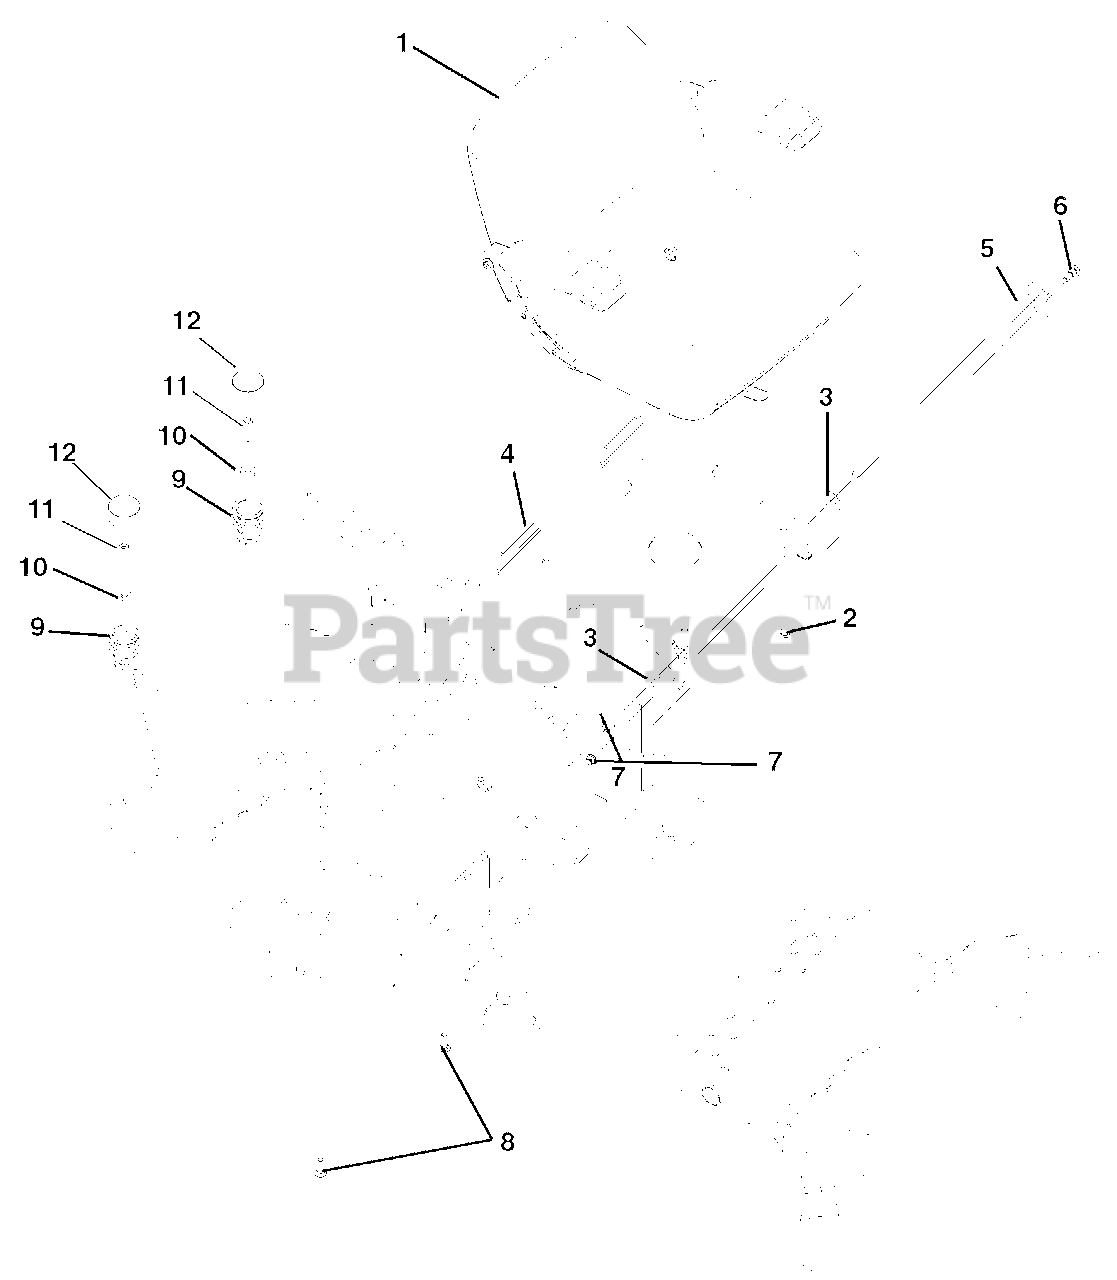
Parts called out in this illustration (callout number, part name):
1	Assembly, Seat with Armrests
2	Nut, Nyloc Flange 5/16-18
3	Bushing, Flange .515 x .750 x .745 x 1.00
4	Weldment, Seat Plate
5	Weldment, Seat Shaft
6	Bolt, Shoulder EP .38-16 x .30 Hex
7	Nut, .38-16 Nyloc Flange
8	Bolt, Round Head Square Neck .38-16 x 1.25 Grade 5
9	Spring, Seat
10	Washer, Flat-Steel .406 x 1.00 x .188
11	Nut, Coupling .375-16 x 1.75
